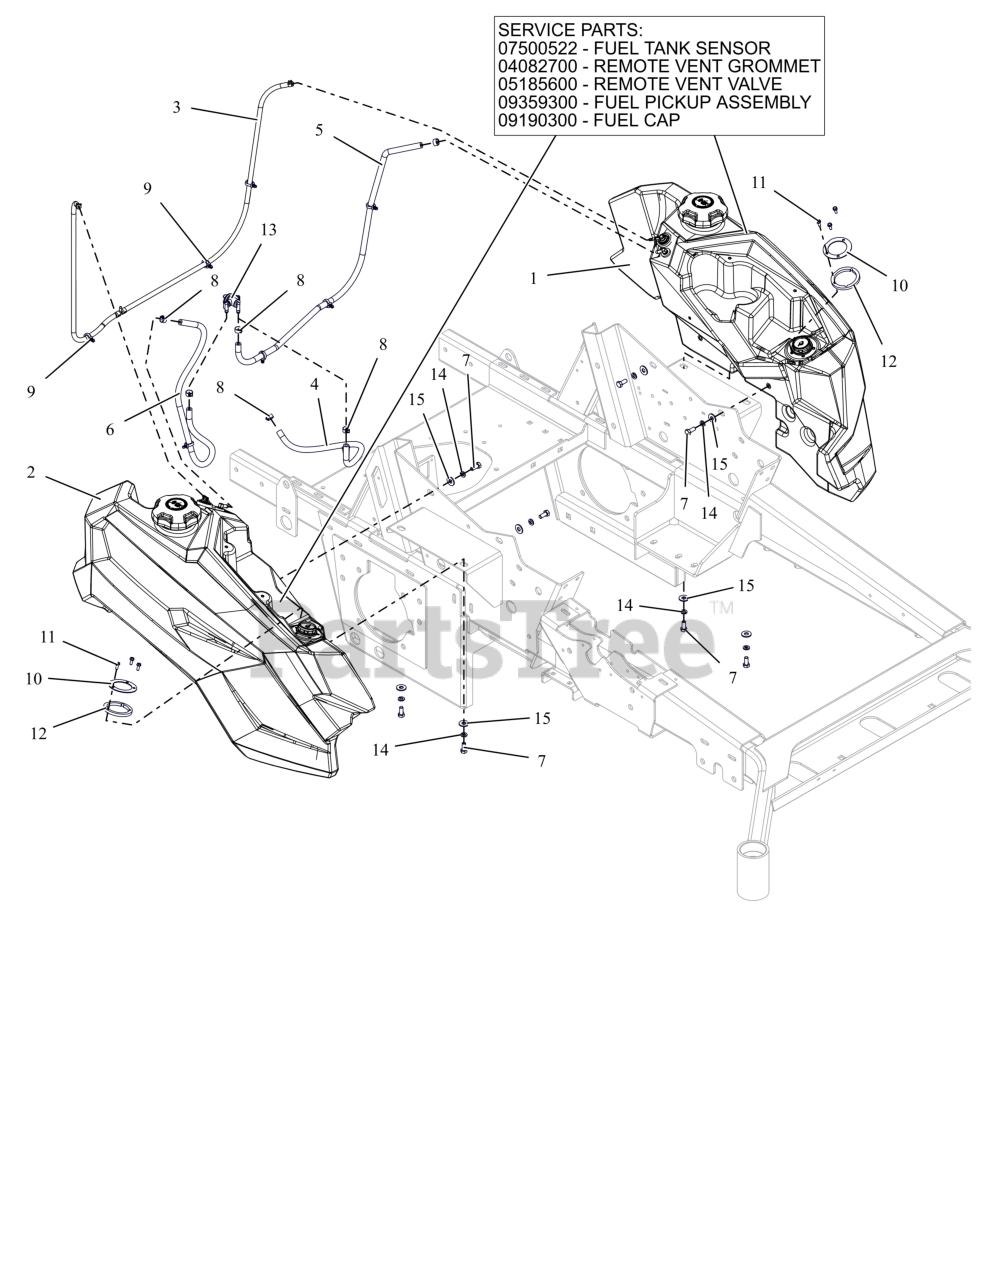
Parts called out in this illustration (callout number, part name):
1	ASM- PT300-500 LH FUEL TANK
1	GAUGE- REMOTE SEALED FUEL
1	GROMMET, REMOTE VENT NITRILE
1	VALVE, COMBINATION VENT 3/16
1	FUEL PICKUP ASSEMBLY
1	CAP, FUEL - 3.50 RATCHET INLET VENT
2	ASM- PT300-500 RH FUEL TANK
2	GAUGE- REMOTE SEALED FUEL
2	GROMMET, REMOTE VENT NITRILE
2	VALVE, COMBINATION VENT 3/16
2	FUEL PICKUP ASSEMBLY
2	CAP, FUEL - 3.50 RATCHET INLET VENT
3	ASM- PT300/500/600 VENT LINE
4	1 INCH OF HOSE, .25 LOW-PERM BULK GAS
5	1 INCH OF HOSE, .25 LOW-PERM BULK GAS
6	1 INCH OF HOSE, .25 LOW-PERM BULK GAS
7	BLT,HEX .31-18X.75 G5 ZCC
8	CLAMP, FUEL LINE
9	CLIP- PUSH-IN X-MAS TREE CABLE
10	RETAINER, FUEL GAUGE (BLACK)
11	SCR-MCH 10-24X.50 HWHSTAINLESS
12	SPCR, FUEL GAUGE RETAINER (BLACK)
13	VALVE, FUEL - WITH MAGNET
14	WSHR,LK-REG .312X.078 ZCC
15	WSHR,FLT .375X.875X.083 ZCC
